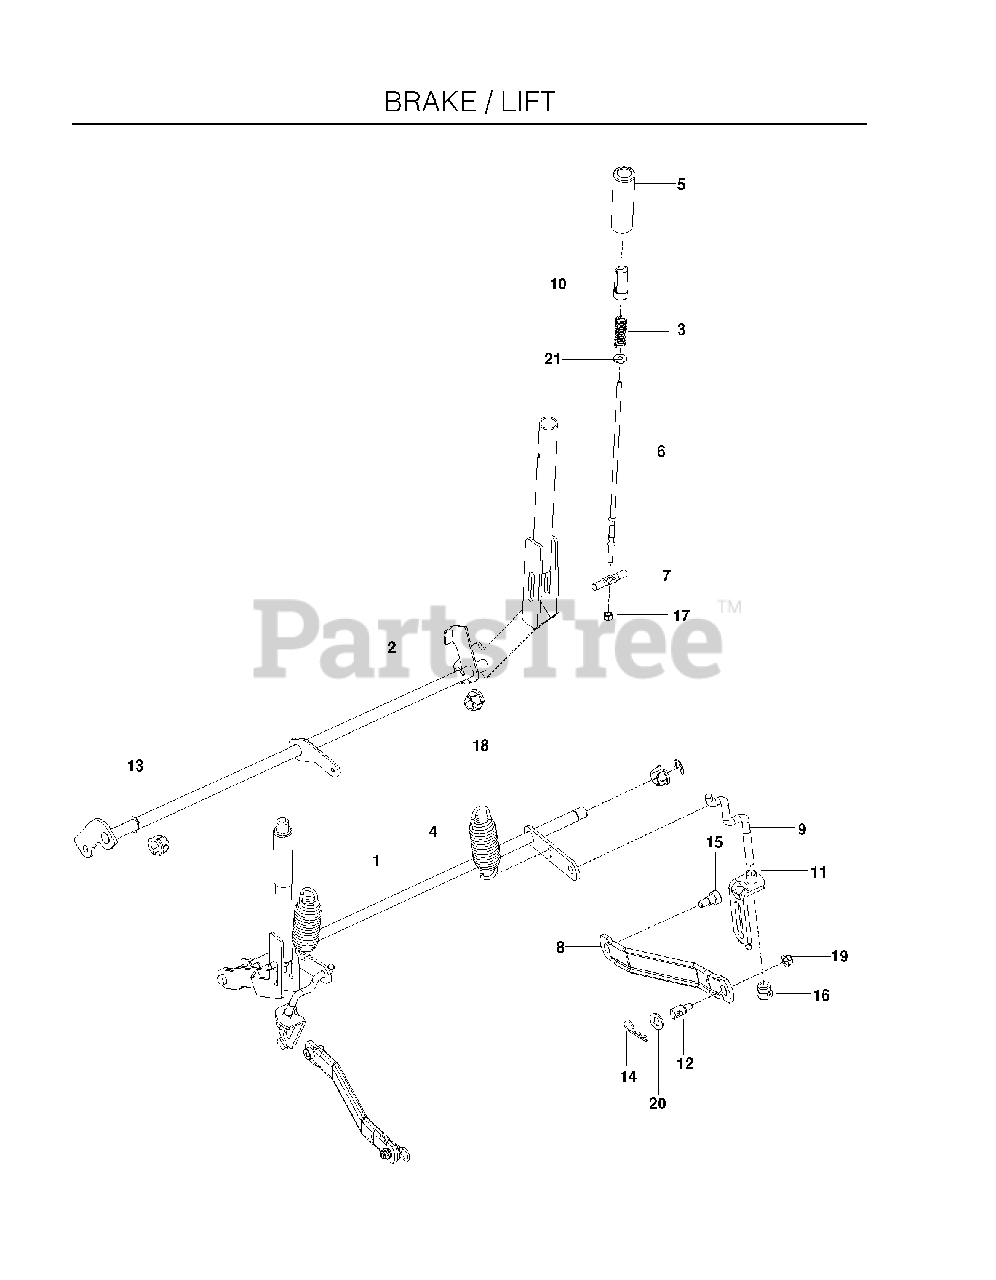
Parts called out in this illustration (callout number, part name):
1	SHAFT, LIFT, MED, BLK
3	SPRING, COMPRESSION
5	GRIP, HANDLE, BLACK
6	ROD, HANDLE RELEASE
7	ROD, LATCH RELEASE
8	ARM.SUSPENSION.MOWER
9	LINK, REAR SUSPENSION
10	BUTTON, PUSH, BLACK
11	ASSEMBLY, BRKT LINK
12	STUD.FASTNER.W/ANTI-ROTATE
13	5/8 E-RING
14	HAIRPIN #4
15	SB 3/8-16 X 3/8 SKT HD ZD
16	NUT, LIFT LINK 7/16-20
17	NUT 1/4-20 NYLOC
18	PLASTIC NUT
19	5/16-18 NYLOC FLANGE NUT
20	WASHER 5/8 FLAT
21	WASHER 1/4 FLAT
